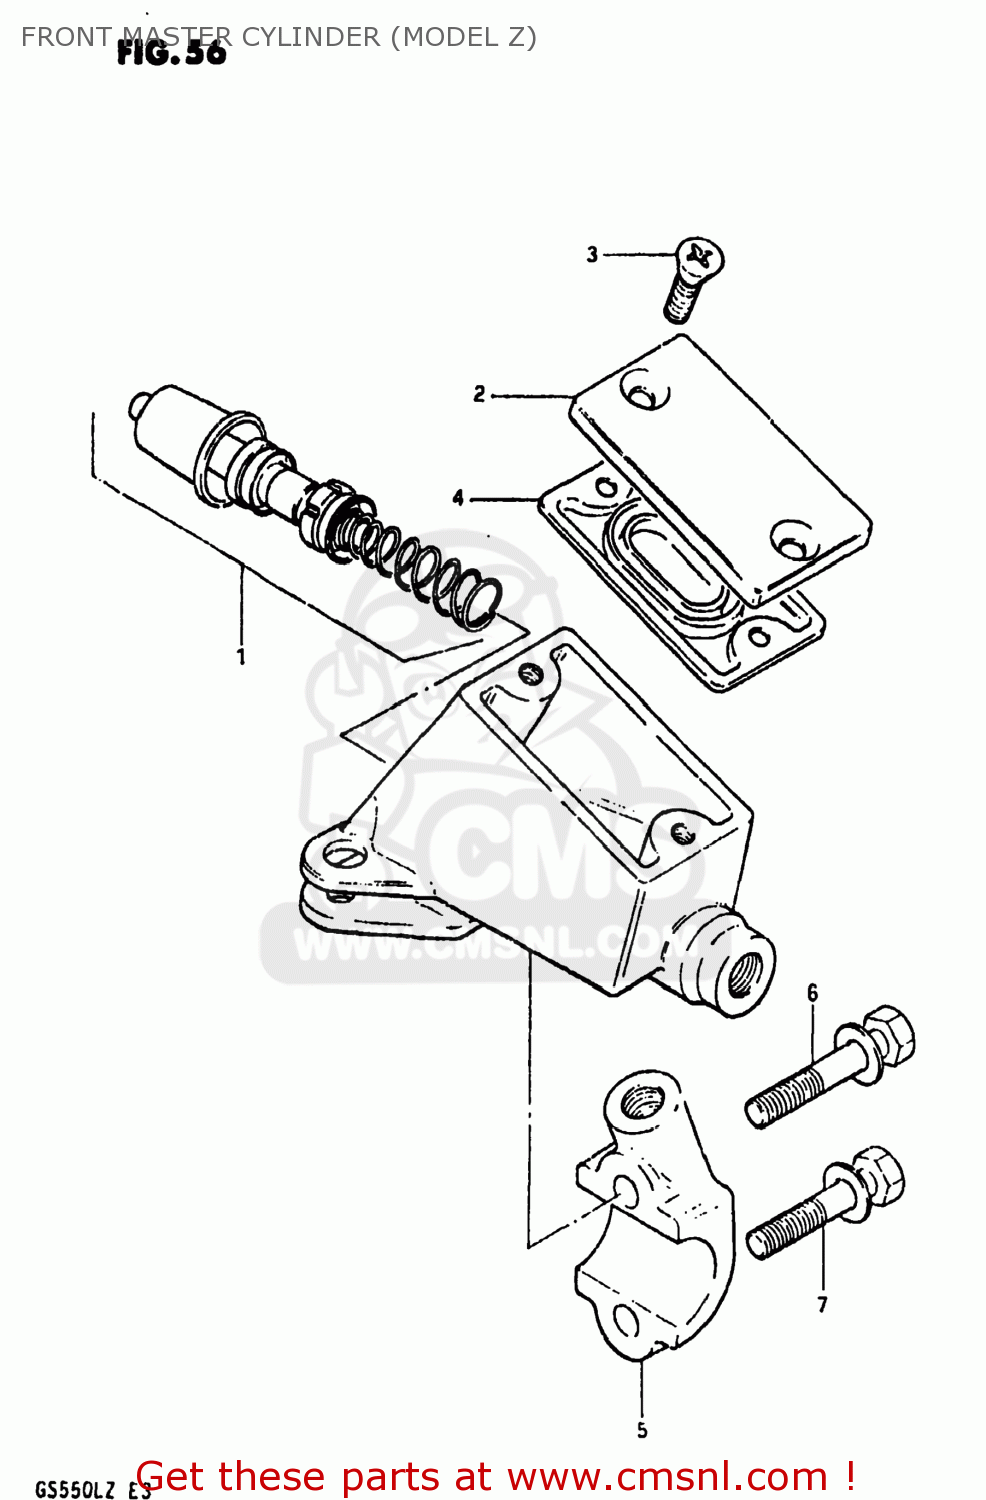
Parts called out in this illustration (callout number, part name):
1	PISTON & CUP SET
2	CAP,MASTER CYLINDER,REAR
3	SCREW,RESERVOIR CAP
4	DIAPHRAGM,MASTER CYLINDER
5	HOLDER,MASTER CYLINDER
6	BOLT,MASTER CYLINDER H
7	BOLT,MASTER CYLINDER H
